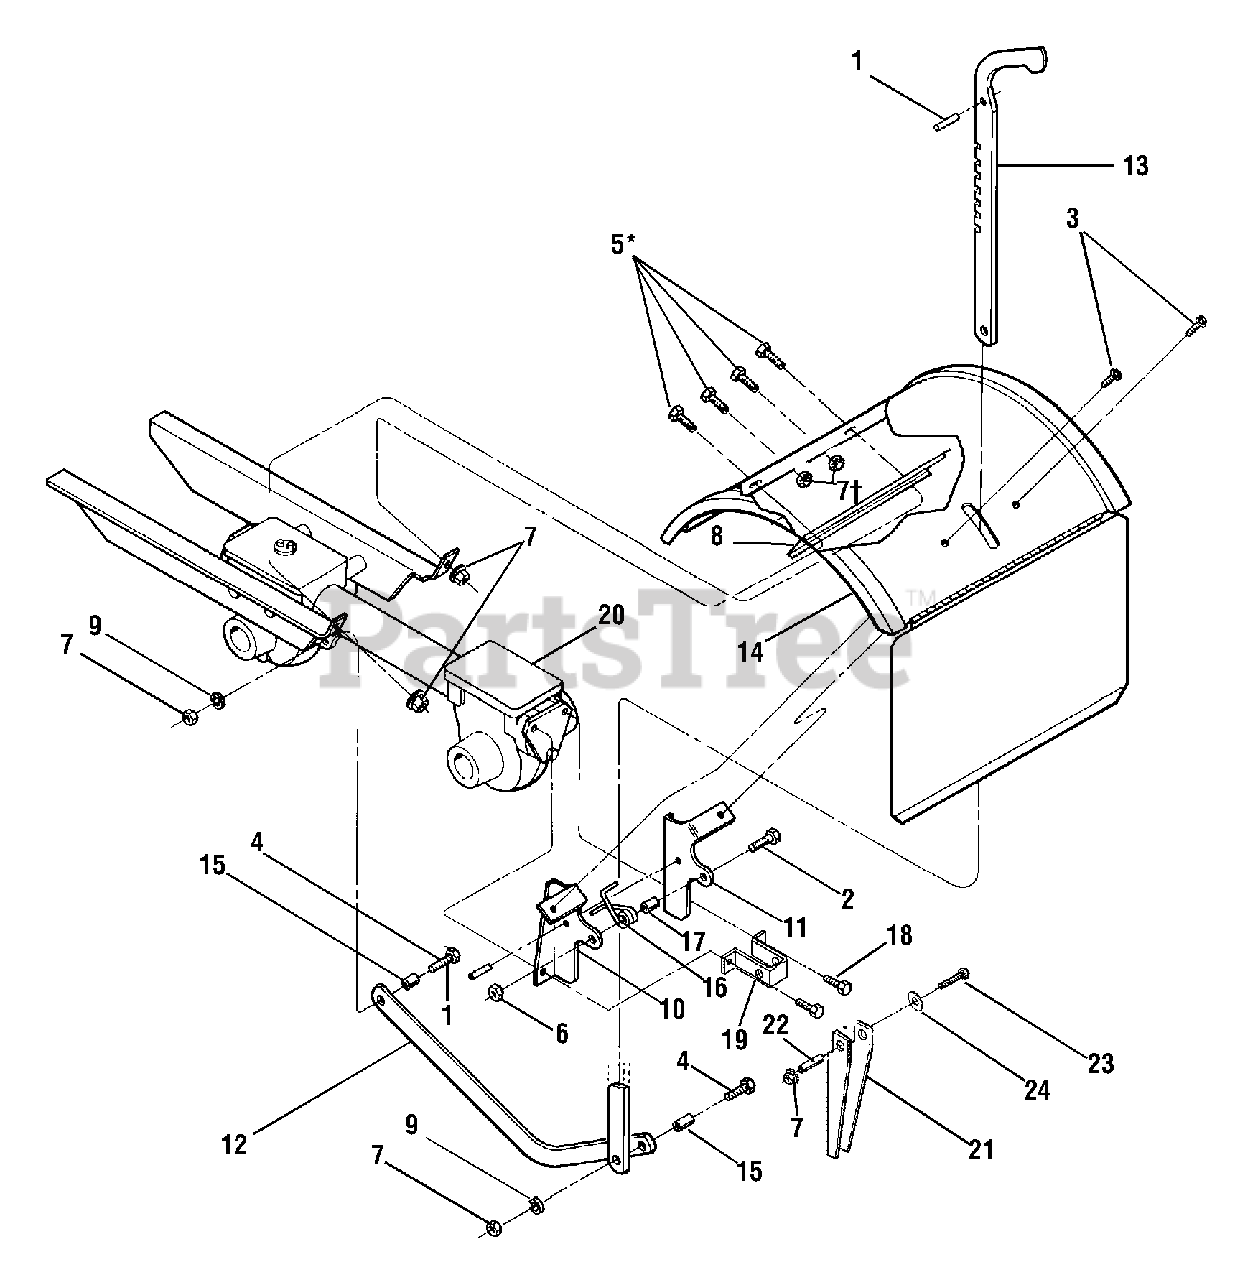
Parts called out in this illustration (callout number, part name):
1	Spirol Pin
2	Hex Hd. Screw, 1/4-20 x 1
3	Screw, Self-Tapping,1/4-20 x 1/2
4	Hex Hd. Screw, 5/16-18 x 1-1/4
5	Hex Hd. Screw, 5/16-18 x 3/4
6	Lock Nut, 1/4-20
7	Lock Nut, 5/16-18
8	Support Bracket
9	Lock Washer, 5/16
10	Hood Bracket, Left Hand
11	Hood Bracket, Right Hand
12	Drag Bar
13	Depth Regulator Lever
14	Tine Hood Assembly
16	Spring, Depth Regulator
18	Hex Hd. Flange Screw, 5/16-18 x 1
21	Reverse Stop Arm
22	Split Spacer,.462 x.328 x 1.63
23	Screw, 5/16-18 x 2.25
24	Flat Washer,.344 x.688 x.065
